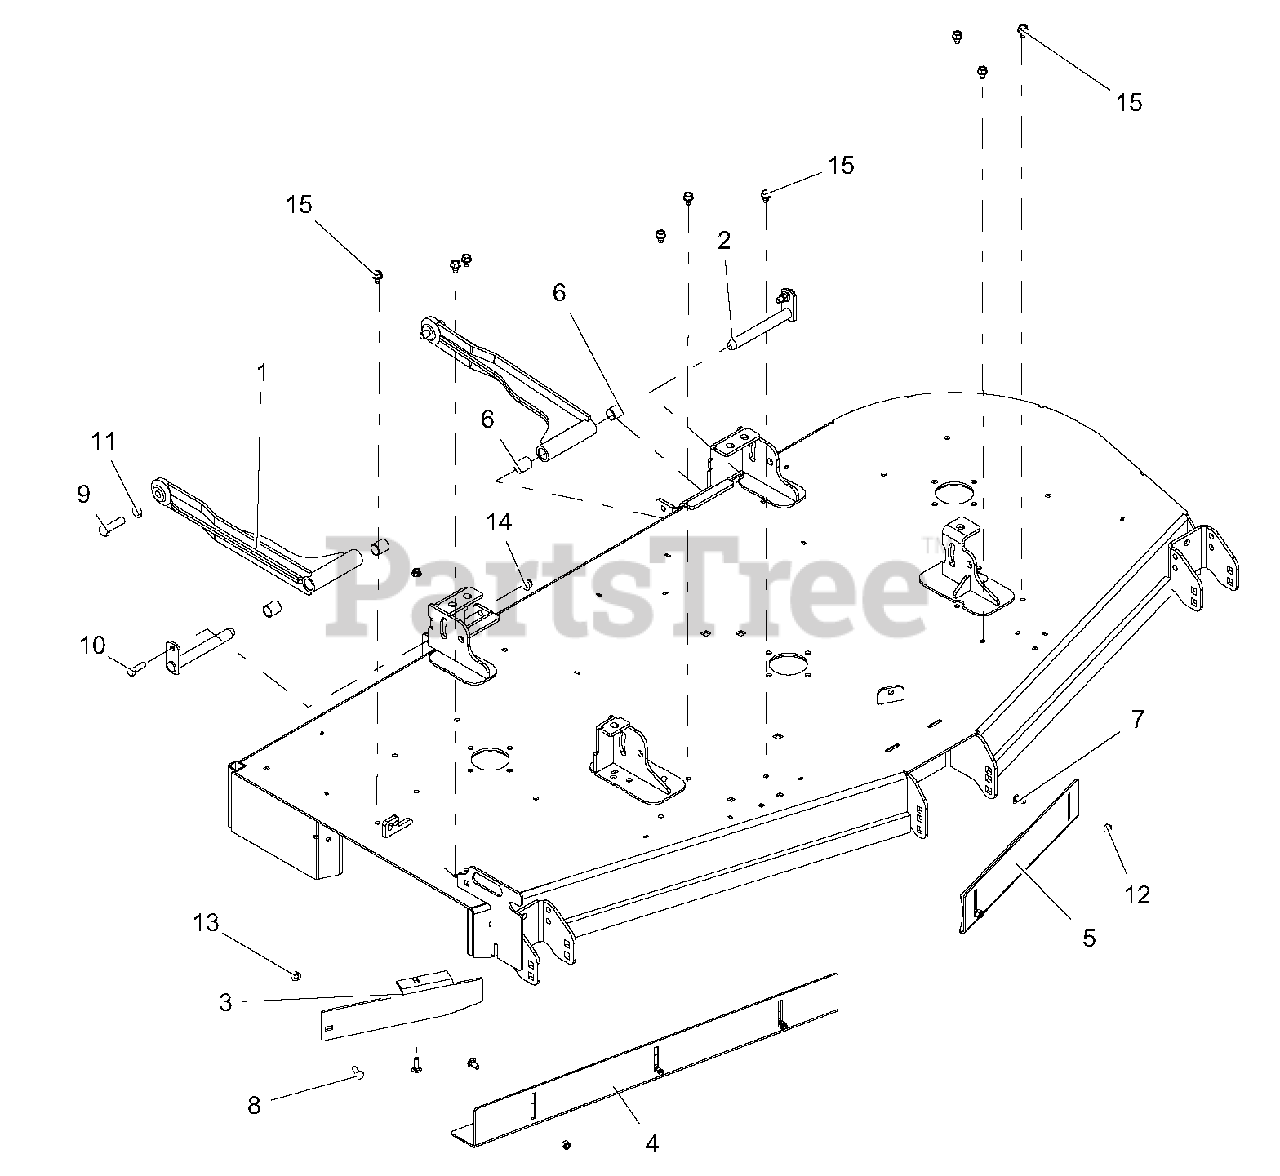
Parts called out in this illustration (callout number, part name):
1	DECK STABILIZER ARM W/BUSHINGS
2	WLDMT, MOWER MTG. PIN
3	BAFFLE, 72" DISCHARGE-RED
4	BAFFLE, 72" RH VACUUM-BLACK
5	BAFFLE, 72" LH VACUUM-BLACK
6	BRG, .75 X .875 X 1.00
7	@BLT-RDHDSQNK .31-18X.75 G5 YWZC
8	@BLT-RDHDSQSHNK .31-18X1.00 G5 Y
9	BLT-HEX .50-13X1.75 GR5 YWZC EP80
10	BLT-HEX .38-16X1.25 GR5 YWZC
11	@WSHR-LK .50X.125 REG YWZC
12	@NUT-LK-NYL .312-18 YWZC
13	NUT-LK-NYL-FLG .31-18 YWZC
14	NUT-LK-NYL-FLG .38-16 YWZC
15	SCR-TAP .38-16X.50 HWH TR YWZ
